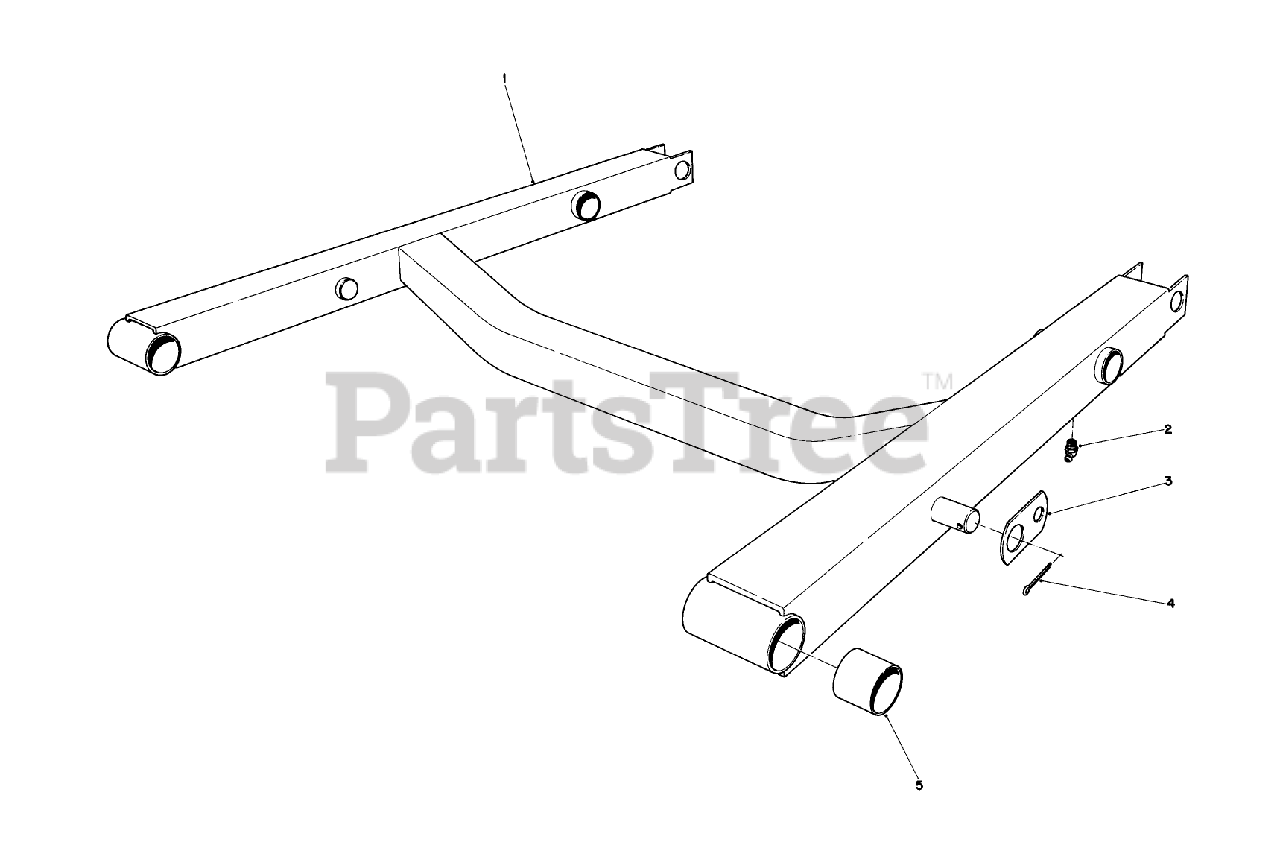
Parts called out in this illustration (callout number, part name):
1	Lift Arm (Incl. Ref. #2 & 5)
2	GREASE FITTING
3	BRAKE SPRNG STRAP R
4	PIN-COTTER
5	7/8 ID X 1.128 X 7/8 LG BSHG
